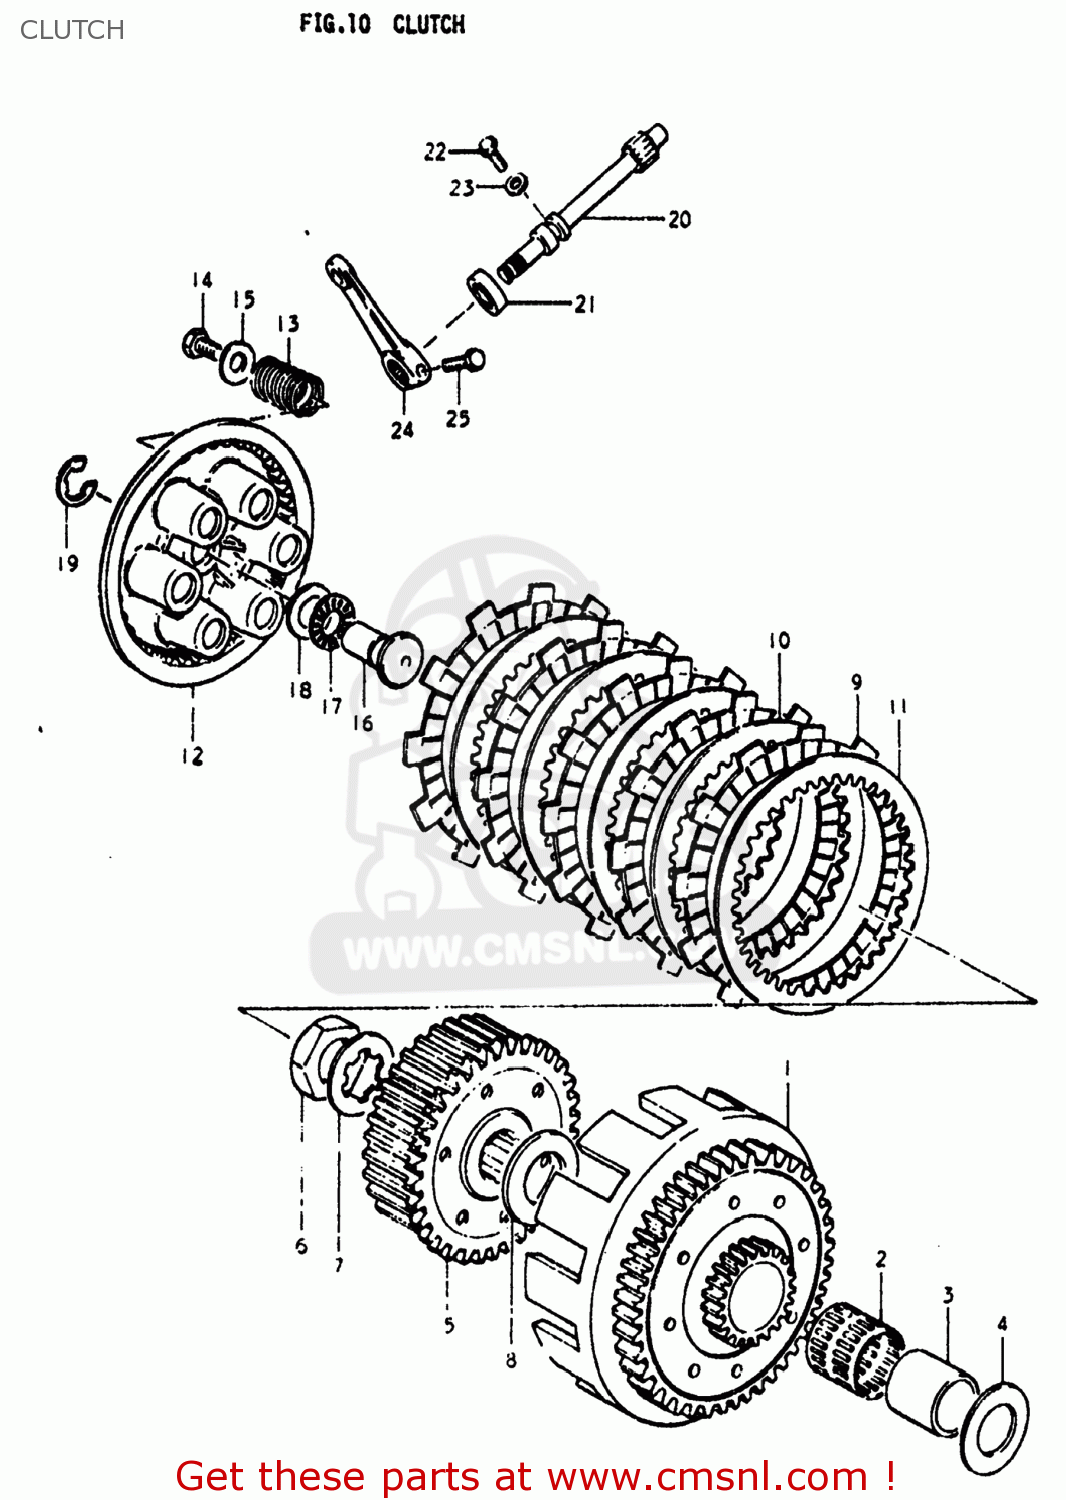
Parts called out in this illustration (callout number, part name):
1	GEAR ASSEMBLY,PRIMARY DRIVE
2	ROLLER BEARING (25X30X2
3	SPACER
4	WASHER(20X38X2)
5	HUB,CLUTCH SLEEVE
6	NUT (20MM)
7	WASHER,LOCK
8	WASHER(20X38X2)
9	PLATE,CLUTCH DRIVE (MCA)
10	PLATE,CLUTCH DRIVEN (NAS)
11	PLATE,CLUTCH DRIVEN(T:2.0) (NAS)
12	DISC,CLUTCH PRESSURE
13	SPRING
14	BOLT, UPPER
15	WASHER
16	RACK,CLUTCH RELEASE
17	BEARING(15X28X2)
18	WASHER
19	E RING 12MM
20	PINION,CLUTCH RELEASE
21	OIL SEAL
22	BOLT(6X12)
23	WASHER
24	ARM,CLUTCH RELEASE
25	BOLT
